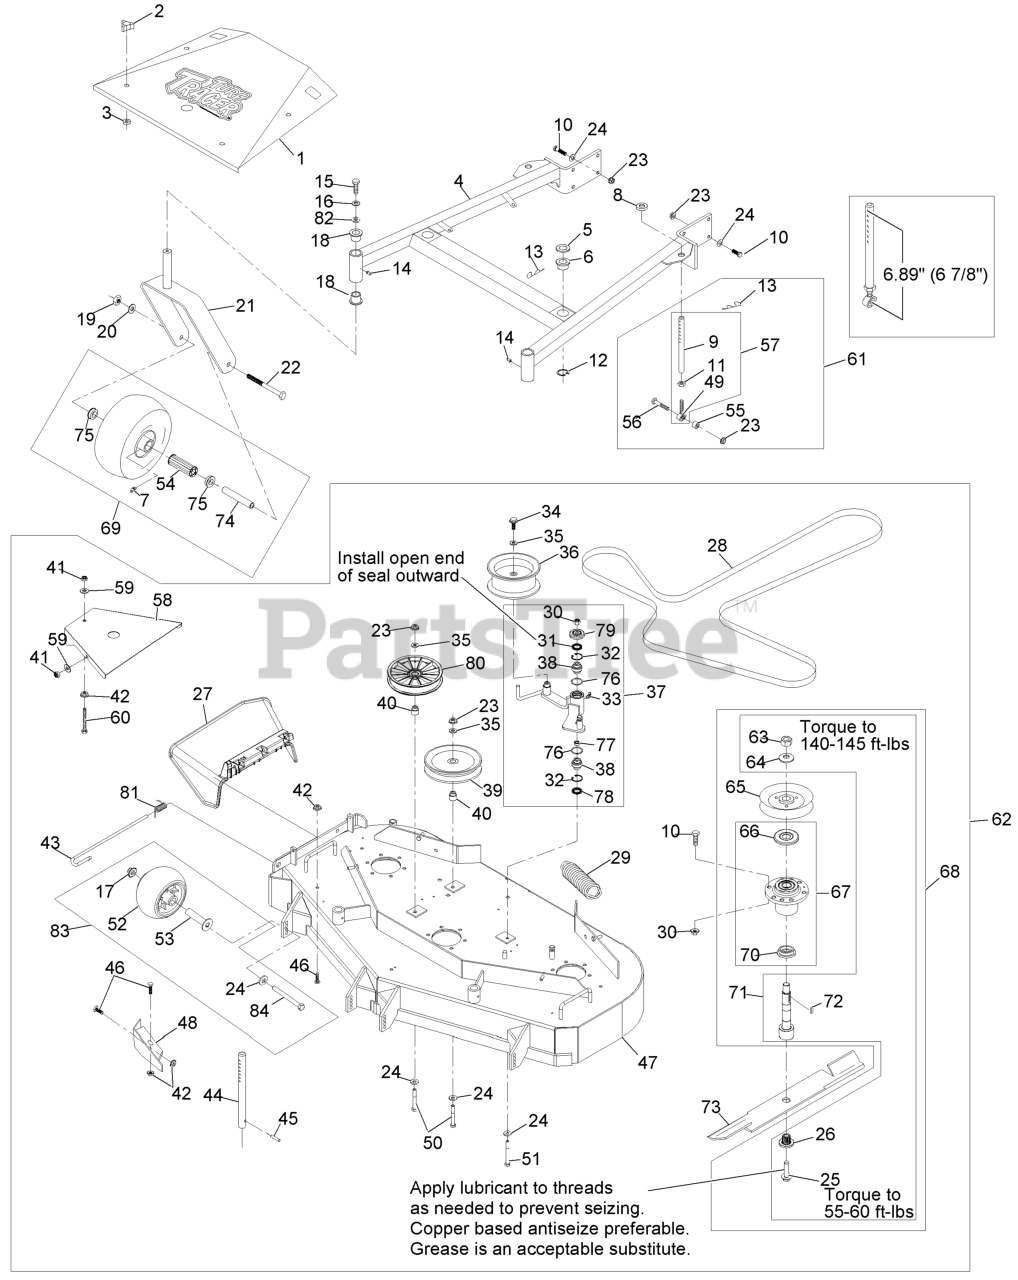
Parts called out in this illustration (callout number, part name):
1	ASM, SHIELD W/ DECALS, 48
2	KNOB-3 PRONG
4	DECK SUPPORT W/BSHGS 48"
5	SPACER-DECK SUPPORT
6	BUSHING-DECK
7	FITTING-GREASE
9	LINK,SUPPORT
10	SCREW-HH
11	NUT-HJ
12	RING-RETAINING
13	PIN,HAIR COTTER
14	FITTING-GREASE
15	SCREW-HH
16	WASHER-LOCK
17	Nut-Nyloc 3/8-16 Flg
18	BEARING-FLANGED
19	NUT-HH
20	WASHER-LOCK
22	SCREW-HH
23	NUT-HHF, WHIZ
24	WASHER-BELLEVILLE
25	SCREW,SEMS 1/2-20 X 2.19
26	BUSHING,SPLINED
27	CHUTE DEFLECTOR XRK M056
28	BELT - V, B
30	NUT-LOCK, NI
31	SEAL-LIP, SINGLE
32	RING-SNAP
33	FITTING-GREASE, 90 DEG
34	SCREW-HHF
35	WASHER-FLAT
36	IDLER-PULLEY, FLAT
37	KIT, DECK IDLER TTHP48&52
38	BEARING-SPHERICAL
39	PULLEY-IDLER
40	BUSHING-IDLER
41	NUT-LOCK, NI
43	PIN-CHUTE
44	ROD,DECK SUPPORT
46	SCREW-HH
47	ASM,DECK W/DECALS TTHP/MH
48	BAFFLE,DOGLEG
49	BALLJOINT
50	SCREW-HH
51	SCREW-HH
52	ROLLER-SCALP, ANTI
53	AXLE, ROLLER
54	BEARING
56	SCREW-HH
58	SHIELD,BELT
59	WASHER-FLAT
60	BOLT,TAP HH
61	KIT,SUPPORT LINK W/PIN
62	Assembly, Cutting Deck Complete
65	SHEAVE,W/HUB 5.72
66	GUARD-BEARING, TOP
67	KIT, CUTTER HOUSING
68	ASM, CUTTER HSG
69	KIT, SP CASTER WHEEL REPL
70	SPACER-GUARD, BOTTOM
71	KIT, SPLINED SPINDLE 103-
72	KEY-RECTANGLE
75	BUSHING
78	SEAL-LIP, DOUBLE
79	GUARD-TOP
80	PULLEY,IDLER 5"
81	SPRING, TORSION
83	KIT, ANTI-SCALP ROLLER
84	SCREW-HH 3/8-16 X 3 3/4 GR 8
